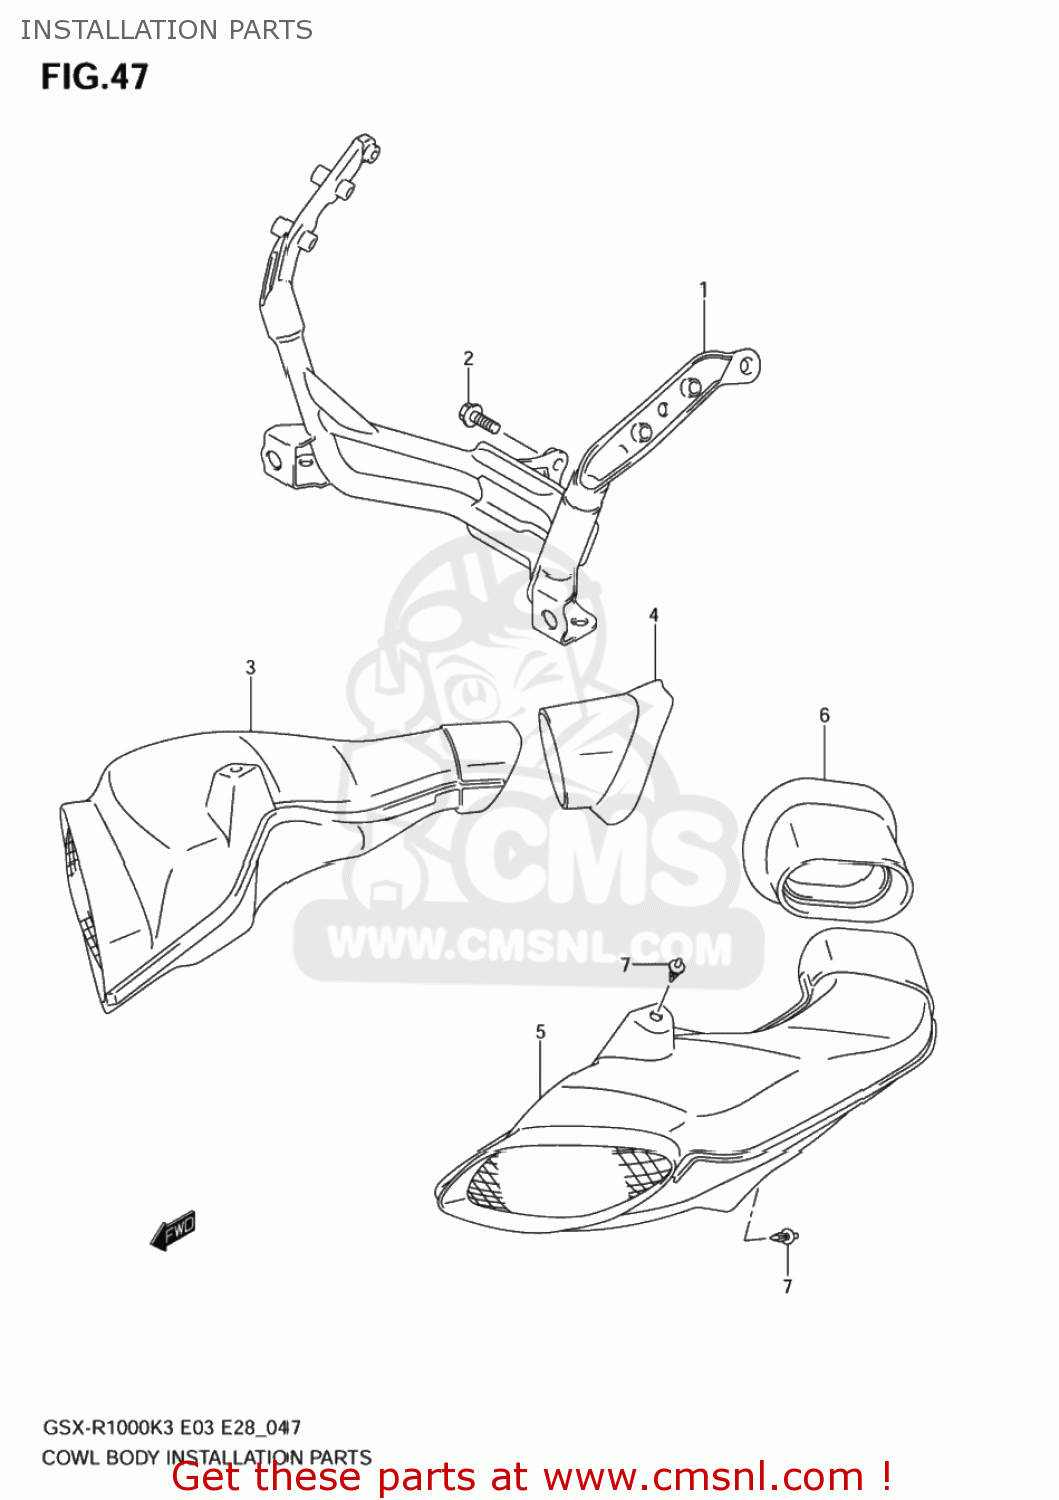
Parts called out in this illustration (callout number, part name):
1	BRACE,COWLING
2	BOLT
3	PIPE ASSY,AIR INTAKE,R
4	MOLDING,AIR INTAKE,R
5	PIPE ASSY,AIR INTAKE,L
6	MOLDING,AIR INTAKE,L
7	CLIP(BLACK)
